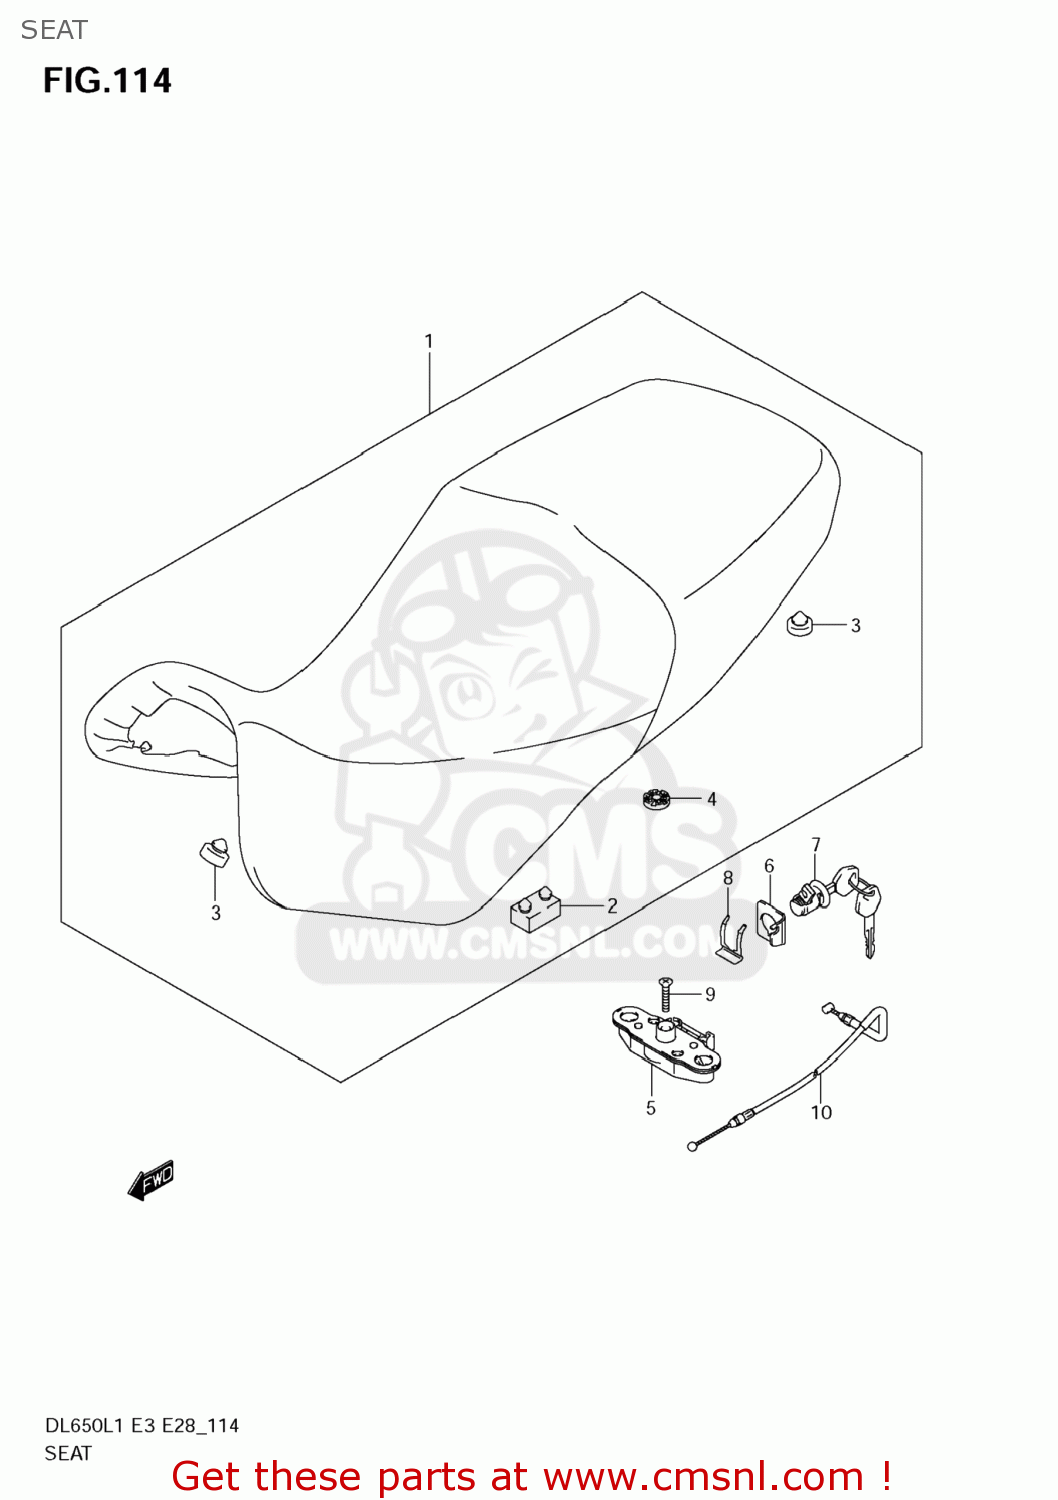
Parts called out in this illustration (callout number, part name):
1	SEAT ASSY
2	CUSHION,SEAT(40X20X15)
3	CUSHION
4	CUSHION,SEAT LOCK(10X22X6)
5	BRACKET,SEAT SUPPORT
6	GUIDE,SEAT LOCK CABLE
7	LOCK SET,SEAT
8	PLATE,SEAT LOCK ASSY
9	SCREW
10	CABLE,SEAT LOCK
